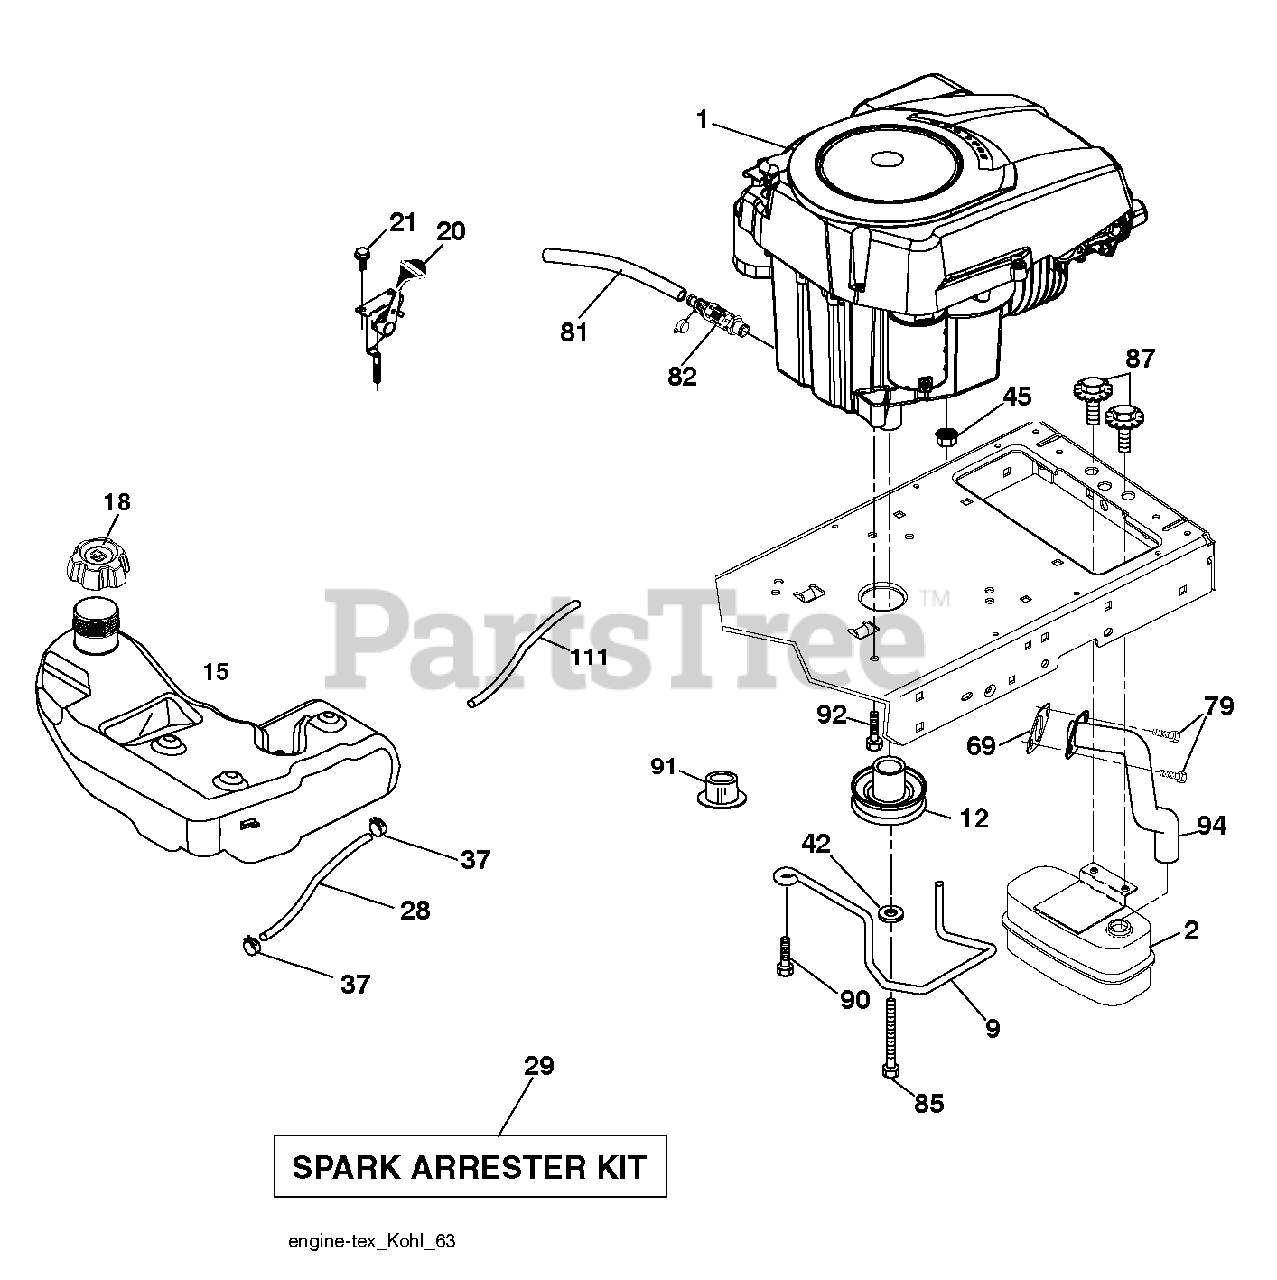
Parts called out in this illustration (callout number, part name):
2	MUFFLER.SINGLE.LRG.BRIGGS.KOHL
9	KEEPER.BELT.ENGINE.3.25
12	PULLEY.ENGINE.5.0.PD
15	TANK.ASM.FUEL.3GA.CARB
18	Fuel Cap Assembly, 3" Black
21	SCREW.#10 X 0.750.BOS (2 2)
28	LINE.FUEL.64"REAR.EMIS
29	KIT.SPARK ARRESTOR(392390 B&S)
37	HOSE CLAMP
42	LOCKWASHER
45	NUT
69	GASKET.EXHAUST.KOHLER
79	SCREW.SOCKET HD.5/16-1
81	TUBE, DRAIN OIL ASM.
82	VALUE.OIL.DRAIN
85	BOLT HEX 7/16-20X4-1/4"
87	BOLT, 5/16-18 X 1 3/4
90	SCREW 3/8-16X1
91	BUSHING.1.375OD
92	SCREW 3/8-16X1
94	Exhaust Tube, Kohler Courage
111	RP PURGE LINE
